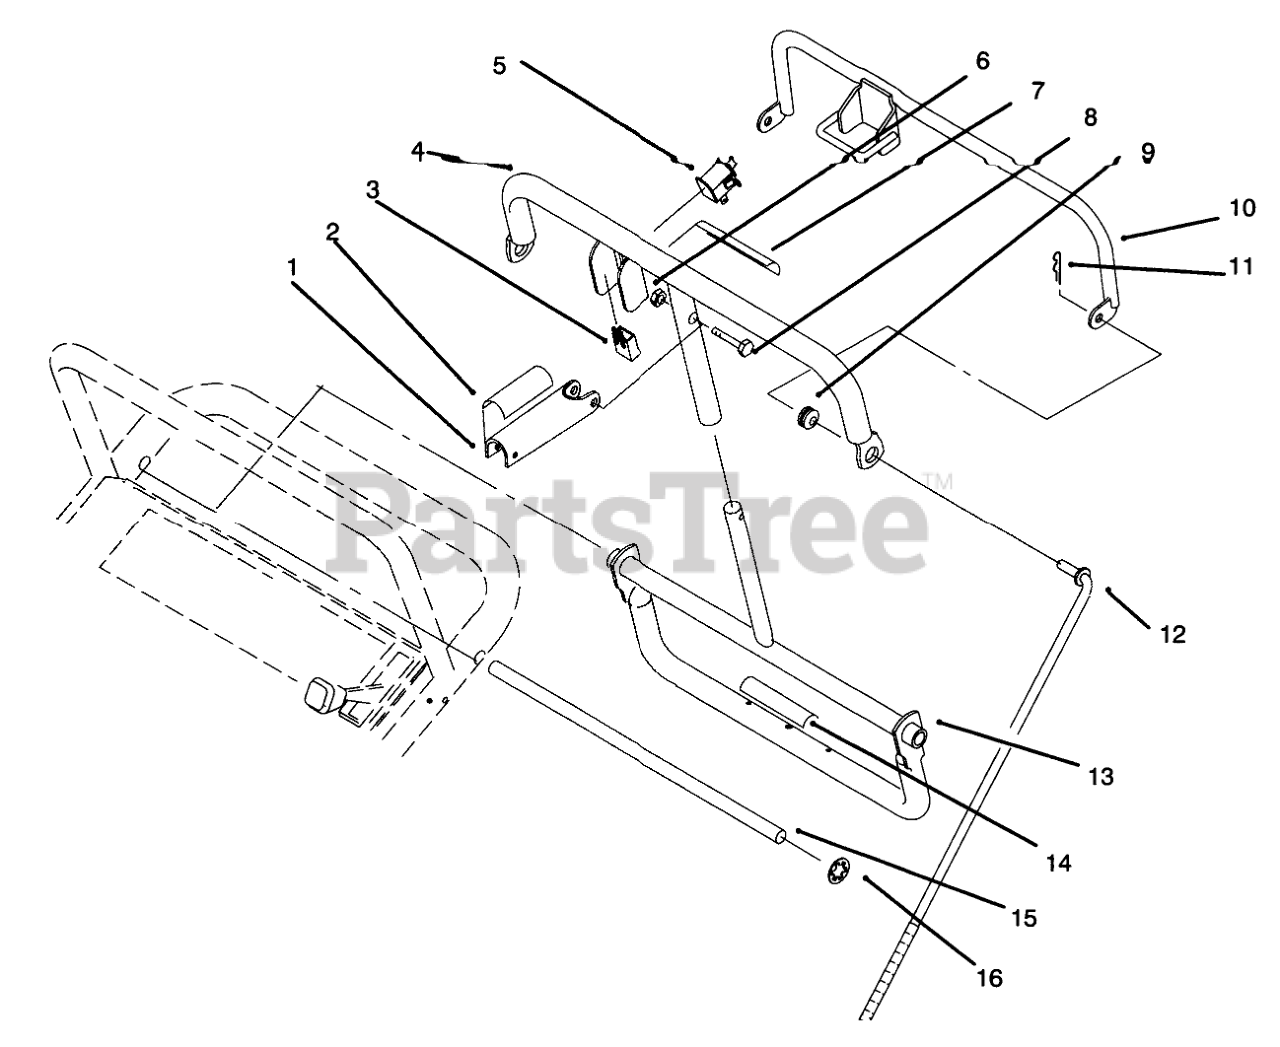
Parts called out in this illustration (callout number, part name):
1	Lever-Parking Brake
2	DECAL-LEVER, PARKING
3	CONNECTOR-BODY
4	DECAL-BAR, CONTROL
5	SWITCH-BAIL
6	NUT-LOCK, NI
7	DECAL
8	SCREW-SHH
9	GROMMET-RUBBER
10	Bail
11	PIN-COTTER
12	ROD-CONTROL
13	Control Pivot
14	DECAL-REVERSE
15	PIVOT ROD
16	NUT-PUSH-ON, CIRCULAR
31	NUT-LOCK, NI
